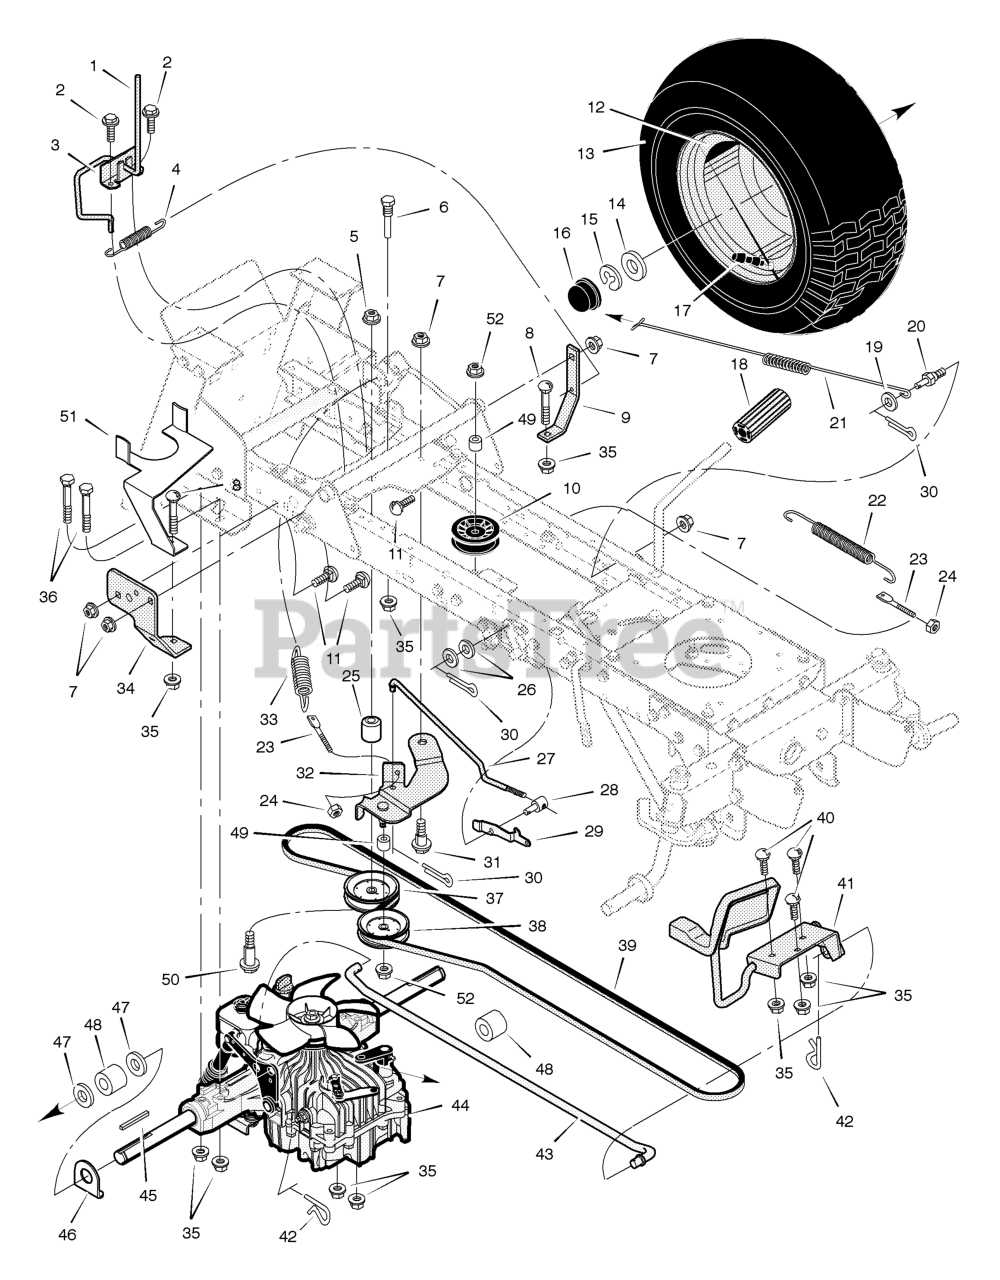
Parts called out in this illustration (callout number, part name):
1	Rod, Cable
3	Bracket, Dump Valve
4	Spring, Extension
5	Locknut
6	Guide, Belt
7	Locknut
8	Bolt, Carriage
9	Bracket, Torque
10	Pulley, Idler
11	Bolt, Carriage
12	Assembly, Wheel and Tire
13	Tire Only *
16	Cap, Hub
17	Stem, Valve
18	Pedal
19	Washer
20	Stud, Threaded
21	Spring, Extension
22	Spring, Extension
23	Stud, Spring Mount
24	Locknut, Flange
25	Spacer
27	Rod, Clutch
28	Nut, Adjusting
29	Latch, Parking Brake
30	Pin, Cotter
31	Bolt, Shoulder
32	Assembly, Idler Arm
33	Spring, Extension
34	Bracket, Torque
35	Nut, Flange
36	Bolt
37	Pulley, Backside Idler
38	Pulley, "V" Idler
39	Belt, Drive
40	Bolt, Carriage
41	Assembly, Pedal
42	Pin, Hair
43	Rod, Hydro Control
44	Transaxle, Hydro Tuff-Torq **
45	Key, Square
46	Washer, Thrust
47	WASHER, 1-1.3 16G FLT
51	Guide, Belt
52	Locknut
